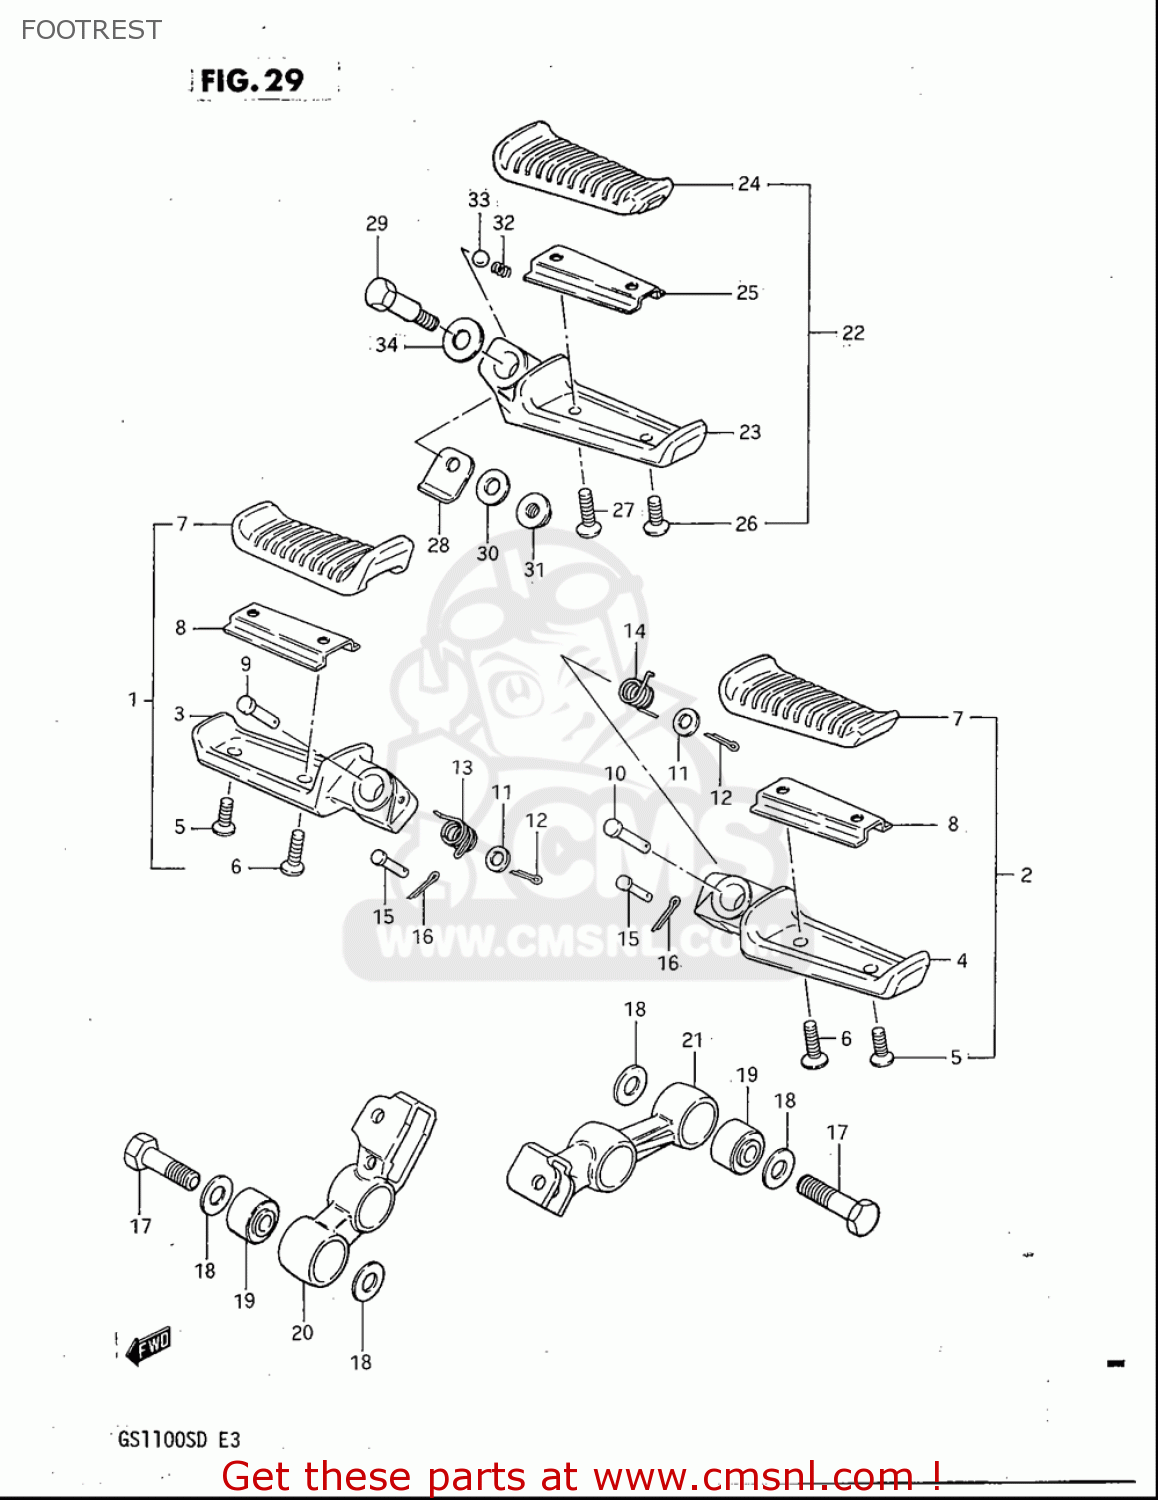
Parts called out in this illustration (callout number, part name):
1	FOOTREST ASSY,FR,R
2	FOOTREST ASSY,FR,L
3	FOOTREST ASSY,FR,R
4	FOOTREST ASSY,FR,L
5	SCREW
6	SCREW
7	RUBBER,FR FOOTREST
8	PLATE,FR FOOTREST RUBBER
9	PIN
10	PIN
11	WASHER
12	PIN
13	SPRING
14	SPRING
15	PIN
16	PIN
17	BOLT(10X38)
18	WASHER(10X20X2.3)
19	BUSH
20	HOLDER,FR FOOTREST,R
21	HOLDER,FR FOOTREST,L
22	FOOTREST ASSY,PILLION,R
24	RUBBER,PILLION FOOTREST
25	PLATE,RUBBER STOPPER
26	SCREW
27	SCREW
28	PLATE,SPRING STOP
29	BOLT(6X45)
30	WASHER
31	NUT
32	SPRING
33	BALL
34	SHIM(8.2X22X0.2)
